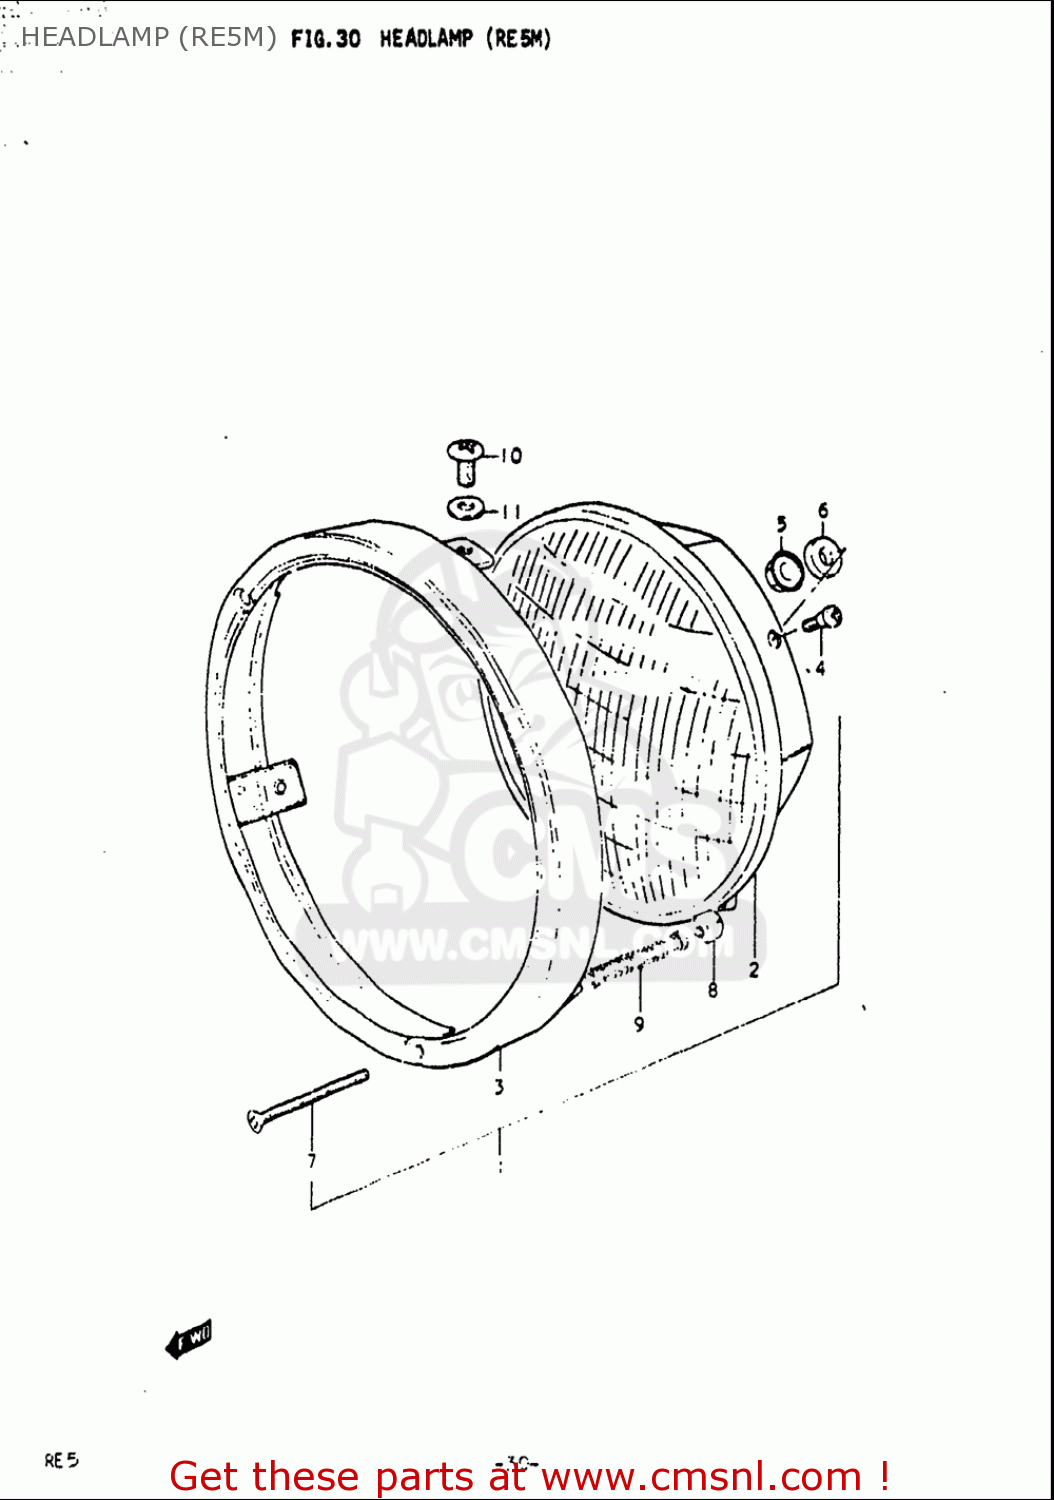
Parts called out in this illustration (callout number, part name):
4	SCREW,HEAD LAMP RIM
5	NUT
11	WASHER
